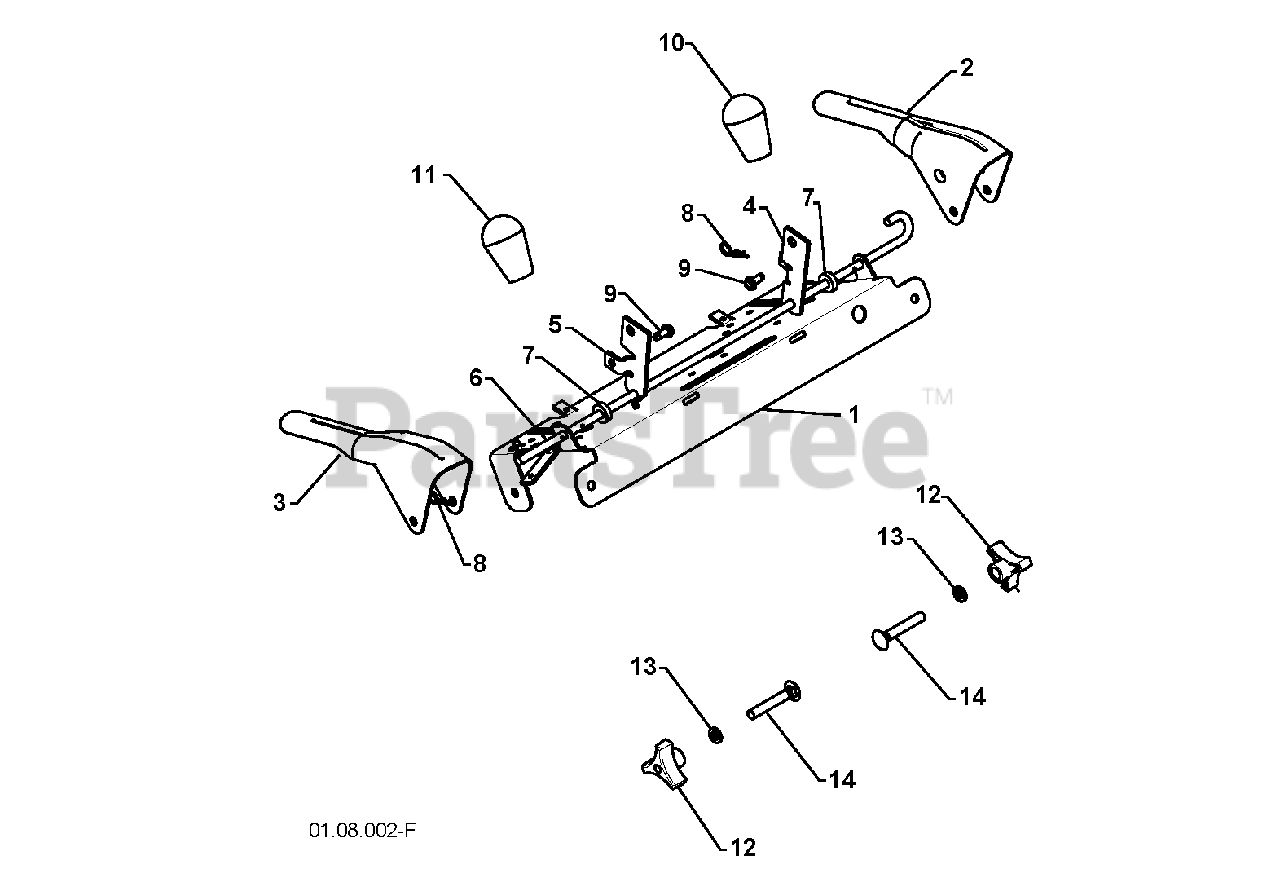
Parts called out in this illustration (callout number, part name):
1	PANEL.CONTROL.PNT.BLACK
2	LEVER.CONTROL.LH.BLACK
3	CONTROLLEVERRH
4	ARM.TRACTION.ROD.YZ
5	ARM.IMPELLER.ROD.
6	BAIL.CONTROL.INTERLOCK
7	SPACER.CONTROL.LEVER
8	SPRING RETAINER
9	SCREW 14-20 X 5/8
10	KNOB LEVER, BLACK
11	RED KNOB SHIFTER
12	KNOB.HANDLE.3/8.TRI-POINT.BLAC
14	BOLT 3/8-16 X 2-1/4
